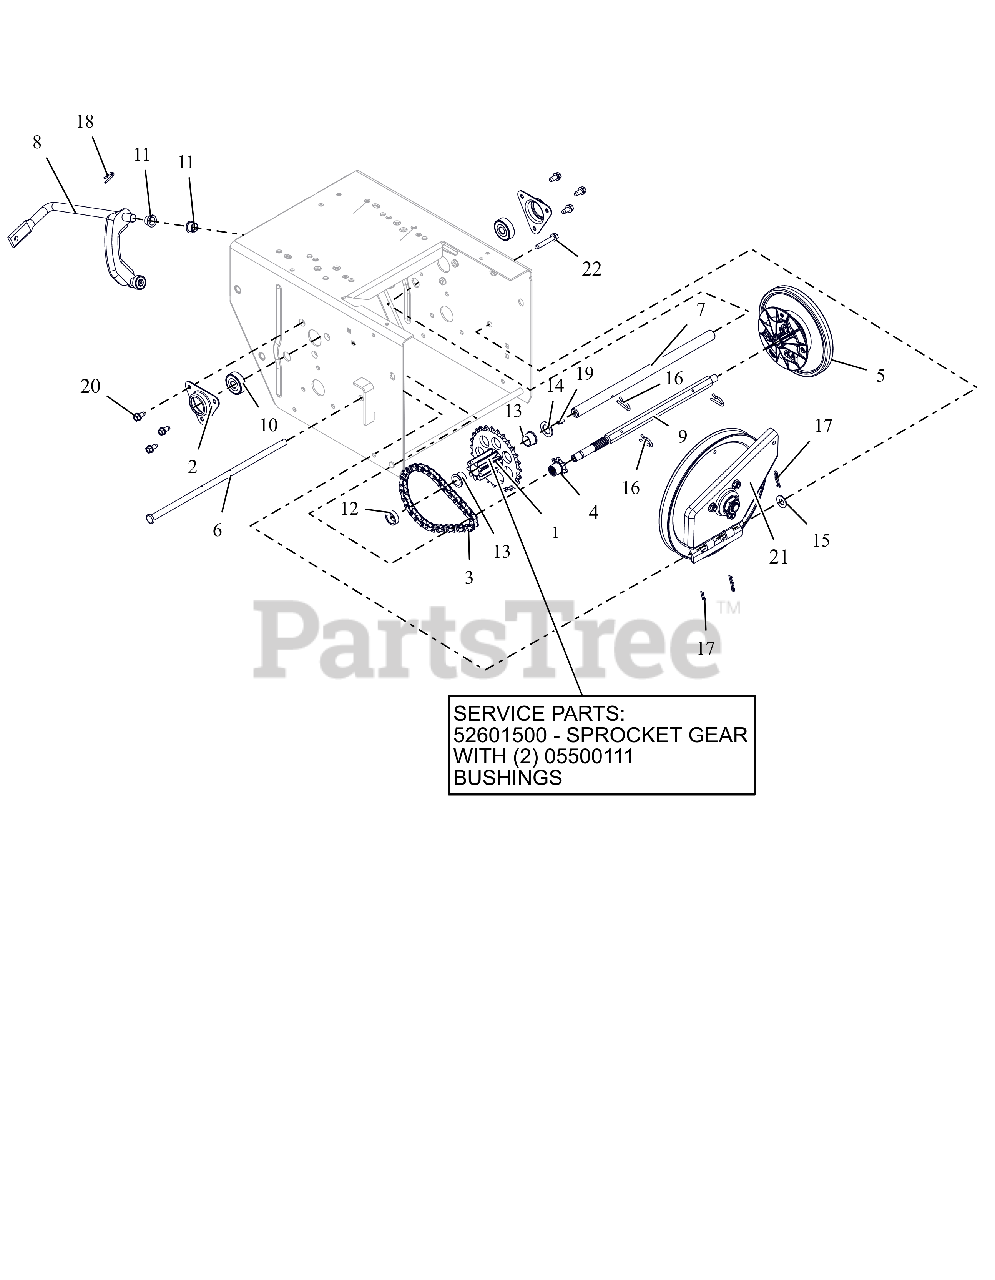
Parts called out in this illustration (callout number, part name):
1	PINION & SPROCKET
1	PINION & SPROCKET W/BUSHINGS
2	FLANGE, BEARING
3	CHAIN - #41, 32 PITCHES
4	SPROCKET, PINION 7T W/SPLINE
5	DISC, FRICTION DRIVE-ASSEMBLY
6	PIN, PIVOT
7	SHAFT, PINION-HARDENED
8	ARM, SHIFT - ASSEMBLY
9	SHAFT, HEX - HEAT TREATED
10	BRG-BALL .437X1.375X.437
11	BUSHING, POLYLINER-.50 SPLIT
12	BSHG-SLV, .635X.880X.305
13	BSHG-FLG .625X.750X.500X.875
14	WSHR-FL-STL .630X1.005X.062 YZ
15	@WSHR-FL-STL.406X.812X.065 YWZ
16	PIN, SPRING CLIP
17	PIN-HAIR, ENDRIES #25 YWZC
18	CLIP, SPRING
19	ZERK,FITTING .25X.125 DRIVE IN
20	SCR-TAP .25-20X.50 HWH TR YWZ
21	PLATE, SWING ASSEMBLY-DEEP
22	@SCR-TAP .25-20X1.50 HWH TR YZ
